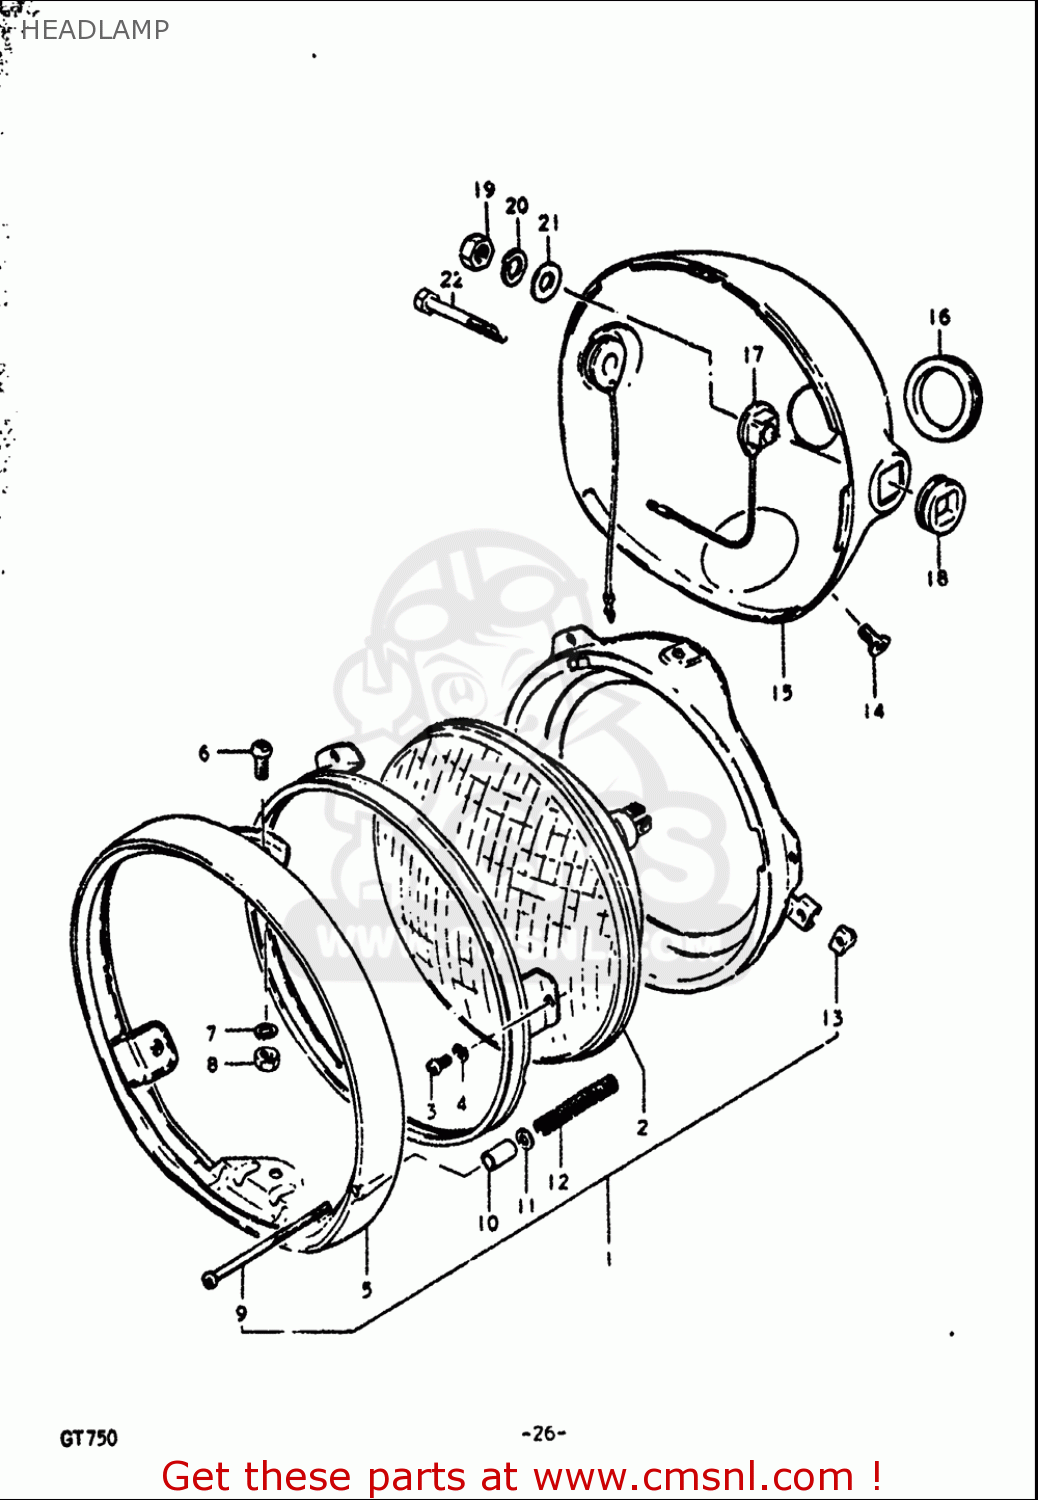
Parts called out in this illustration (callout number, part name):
3	SCREW
4	WASHER,LOCK
6	SCREW
7	WASHER,LOCK
8	NUT
9	SCREW
11	WASHER
13	NUT
14	SCREW
16	CUSHION,HOUSING
17	PIECE,ADJUSTER
18	GROMMET,HEADLAMP HOUSING
19	NUT
20	WASHER,LOCK
21	WASHER
